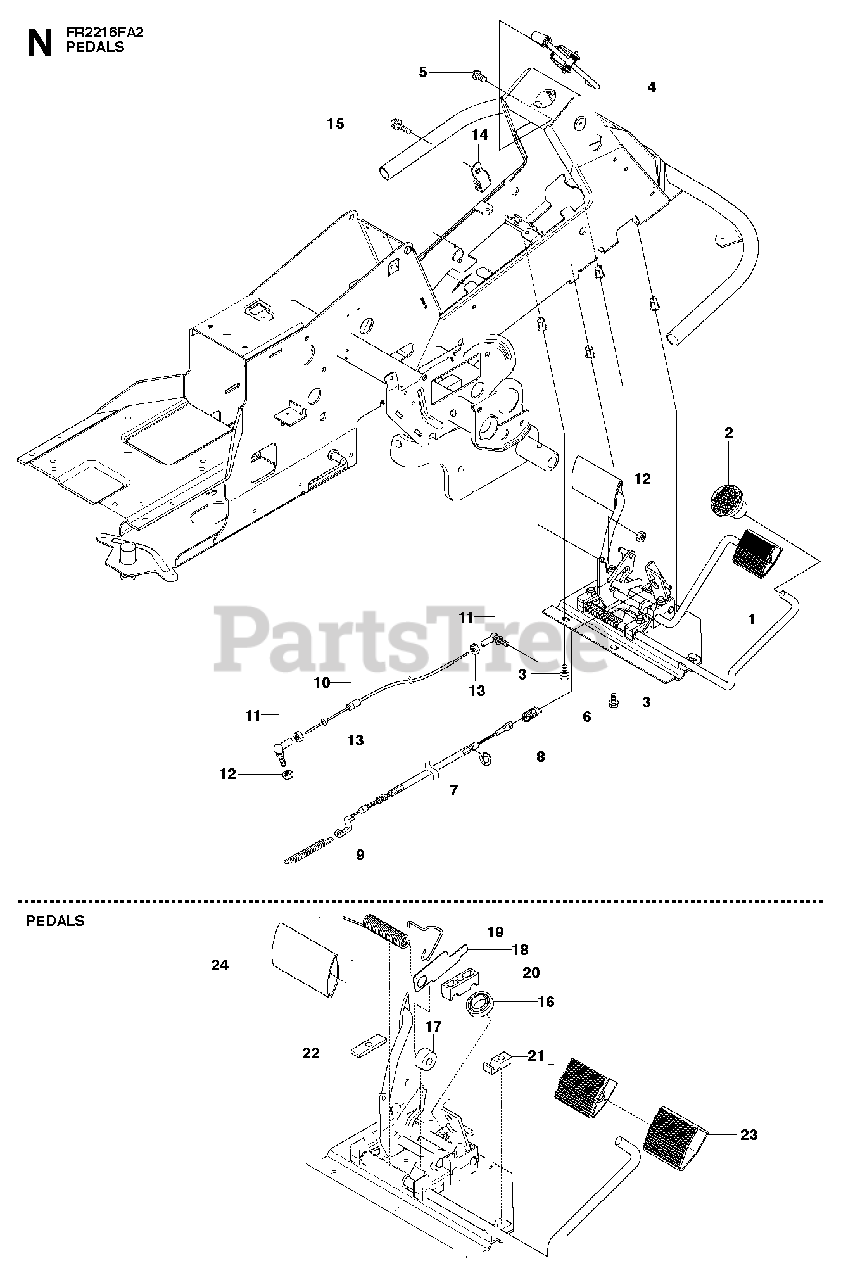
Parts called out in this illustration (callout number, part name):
1	PEDAL ASSEMBLY
2	KNOB
4	BRAKE LEVER ASSY
7	BRAKE WIRE
10	CONTROL CABLE
11	CONNECTOR
12	LOCKNUT M5
16	BALL BEARING 6002-2RS1
17	ROLLER
18	PLATE
19	SPRING
20	PEDAL SHAFT CLAMP
21	SUPPORT
22	PLATE
23	PEDAL RUBBER
